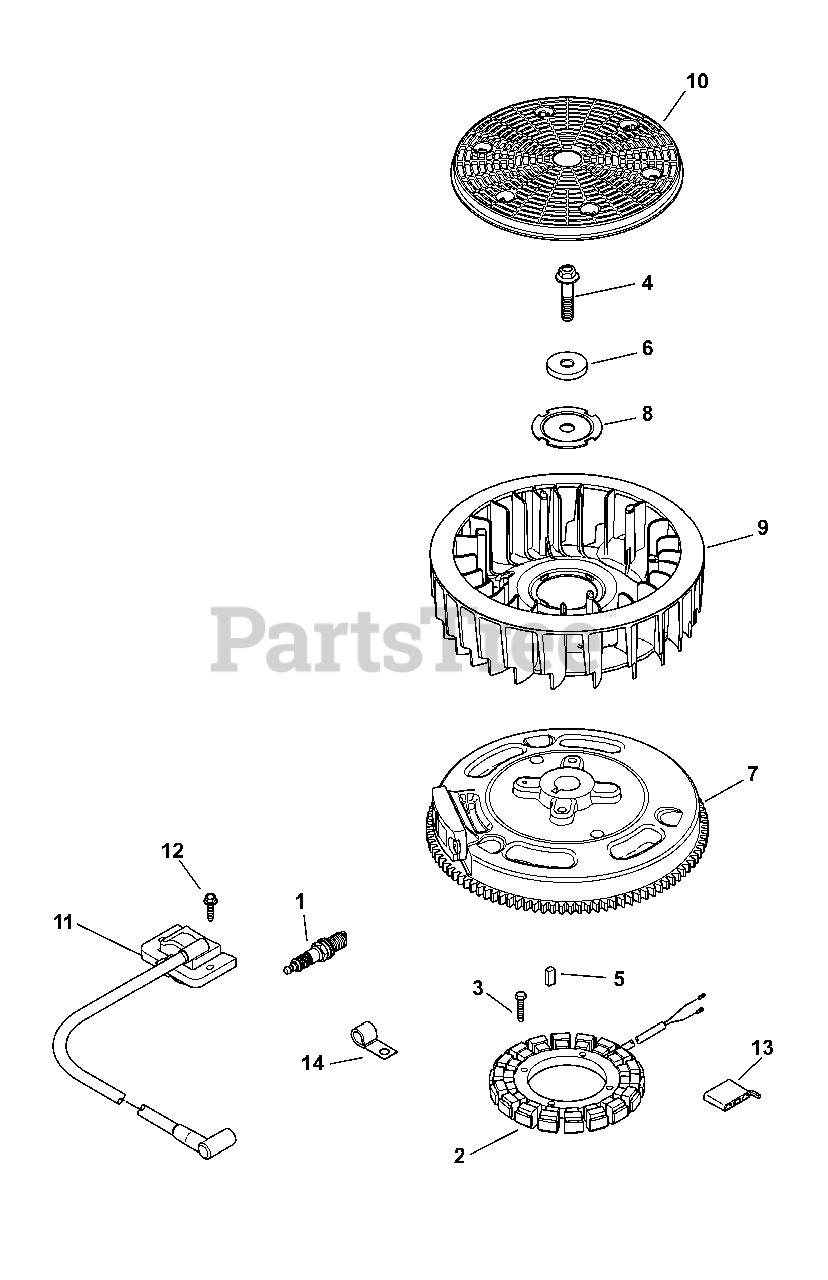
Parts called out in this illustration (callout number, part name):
1	Spark Plug
2	25 Amp Stator Assy. Kit
3	Thd. Frm. Screw, M5 x 0.8 x 30
4	Hex Flange Screw
7	Flywheel Assembly
8	Fan Mounting Plate
9	Fan
11	Ignition Module Kit
12	Flg. Thd. Frm. Screw, M5 x .8 x 20
